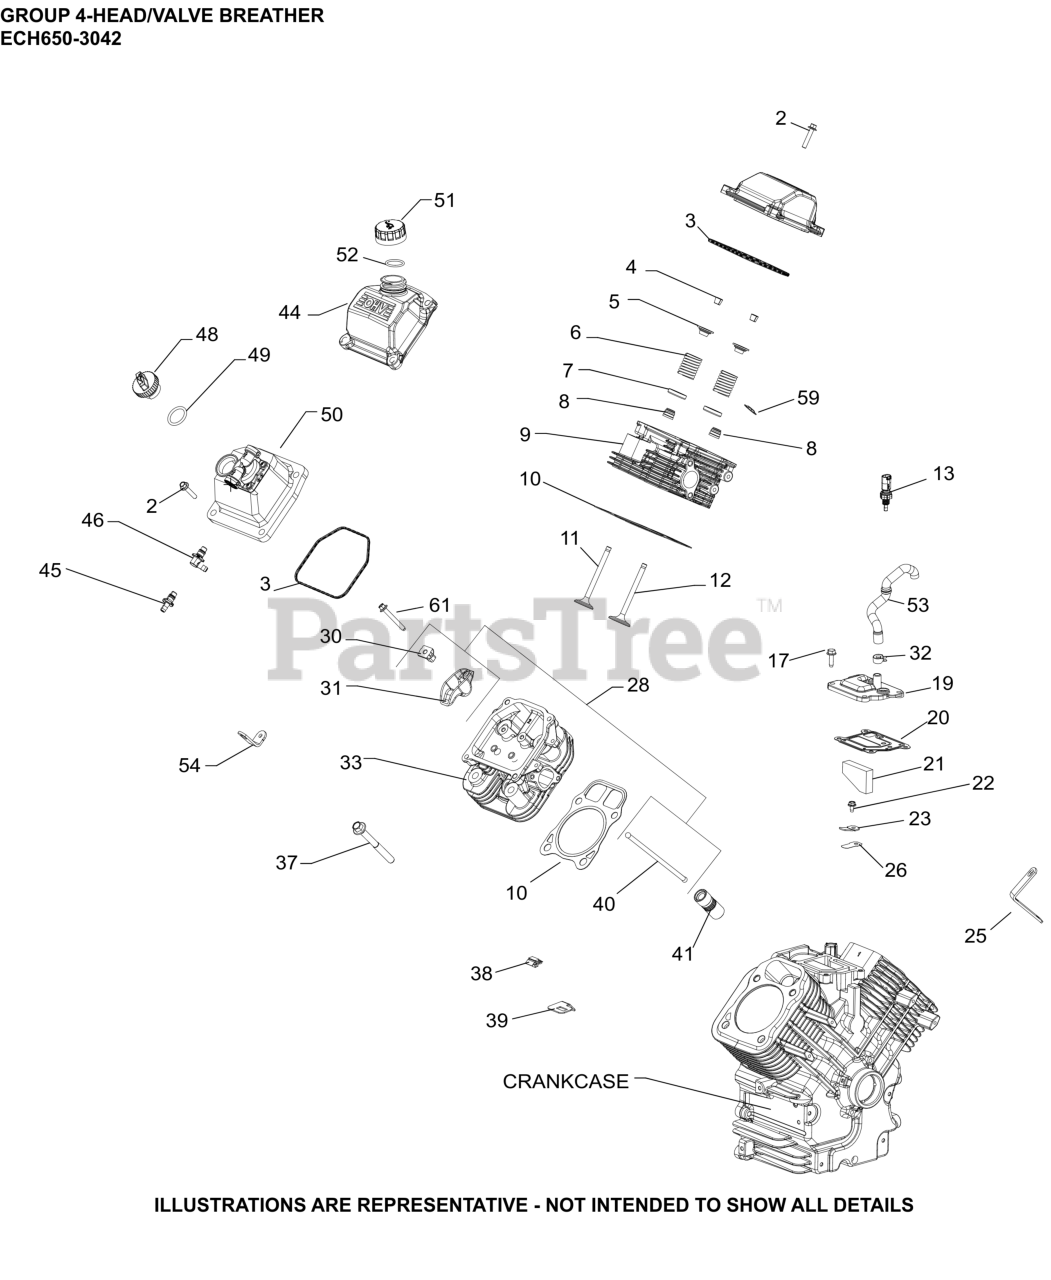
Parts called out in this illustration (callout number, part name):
2	SCREW, FLG M6X1.0X30-USE 25 086 797-S
3	O-RING (YELLOW), VALVE CO
4	KIT, RETAINER
5	CAP, VALVE SPRING
6	SPRING, VALVE
7	RETAINER, SPRING
8	SEAL, VALVE BAND
9	KIT, CYLINDER HEAD (#1)-(#2481803S)
10	KIT, GSKT CYL HD (C22-23 674CC)
11	VALVE, EXHAUST
11	VALVE, EXHAUST (.25)
12	VALVE, INTAKE (STD)
12	VALVE, INTAKE (.25)-(#DSC)
13	SENSOR, TEMPERATURE
17	SCREW, THREAD FORMING
19	COVER, BREATHER
20	GASKET, BREATHER
21	FILTER, BREATHER
22	SCREW, FLG THD FRM M5X.8X10
23	RETAINER, REED
25	STRAP, LIFT-USE 25 445 06-S
26	REED, BREATHER
28	KIT, VALVE TRAIN
30	PIVOT, ROCKER ARM
31	ARM, ROCKER
32	SPRING CLAMP, HOSE
33	KIT, CYLINDER HEAD (#2)-(#2481804S)
37	SCREW, FLG M10X1.5X90
38	CLIP, O2 SENSOR
39	BRACKET, OXYGEN SENSOR
40	ROD, PUSH
41	LIFTER, VALVE HYDRAULIC-USE 25 351 11-S
44	KIT, VALVE COVER-OIL FILL
45	KIT, STRAIGHT FITTING
46	KIT, 90 DEG. FITTING
48	CAP ASSY, OIL FILL (YELLOW)
50	KIT,VALVE COVER-FUEL PUMP
51	KIT, OIL FILL CAP (BLACK)
52	O-RING, DIPSTICK
53	BREATHER, HOSE (EFI H/S, LPAC)
54	STRAP, LIFTING
59	RETAINER, VALVE GUIDE (KM)
NI	SCREW, HEX FLANGE
